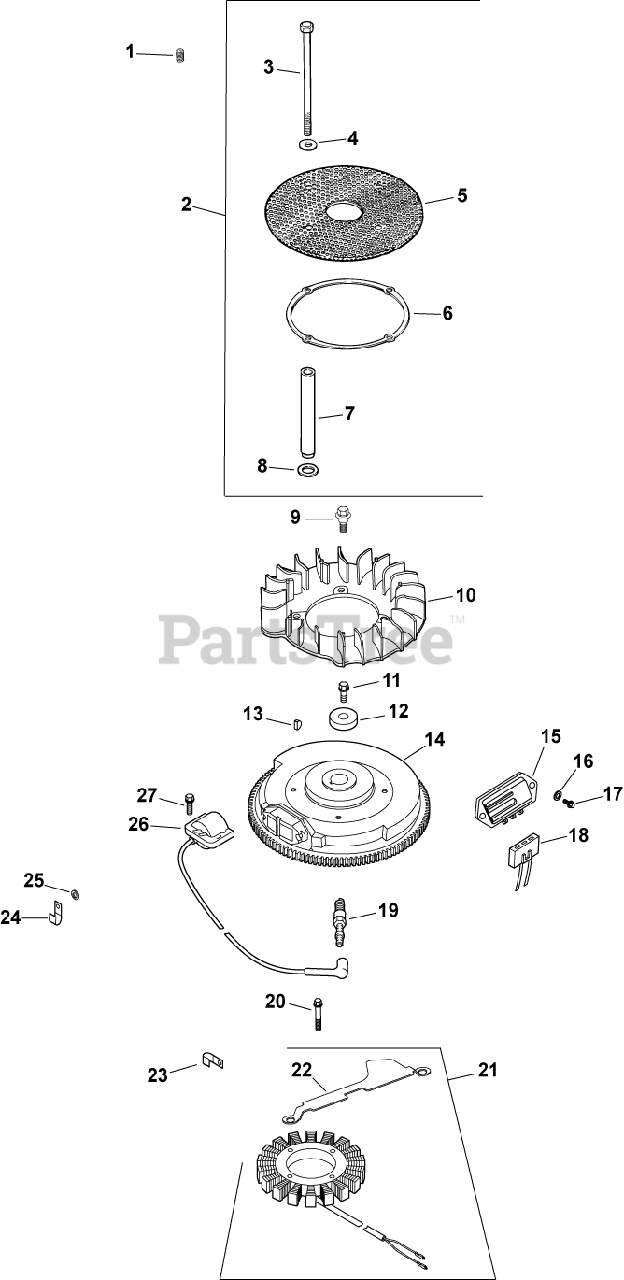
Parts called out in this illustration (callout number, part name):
1	SCREW, SKT SET #10-24X1/4"
2	KIT, CHOPPER SCREEN
3	SCREW, CAP M6X1.0X99.5
4	WASHER, FLAT 1/4" (O.D. 5/8")
5	SCREEN, GRASS-USE 24 162 41-S
6	RING, SUPPORT USE 25 141 08-S
8	WASHER, SPRING 10 MM
9	BOLT, SHOULDER
10	FAN (KM)-USE 24 157 15-S
11	SCREW, FLG M10X1.5X45 - (#25086361S)
12	WASHER, FLAT 13/32"
13	KEY, 3/16" X 5/8"
14	FLYWHEEL, PAINTED-USE 24 025 55-S
15	REG/RECT-15 AMP (KM)-USE 41 403 10-S
16	WASHER, FLAT 1/4" (O.D. 1/2")
17	SCREW, PHL HD #11-16X7/8"
18	CONNECTOR, BODY (KM)-USE 25 155 41-S
19	PLUG, SPARK (PRO SERIES)
20	SCREW, M5X0.8X25 - (#25086402S)
21	STATOR KIT - USE 237878-S
22	BRACKET, STATOR WIRE
23	CLIP, CABLE
24	CLIP, TUBE & WIRING (KM)
25	WASHER, FLAT 1/4" (O.D. 1/2")
26	MODULE, IGNITION-USE 24 584 45-S
27	SCREW, FLG THD FRM M5X.8X20-(#25086399S)
